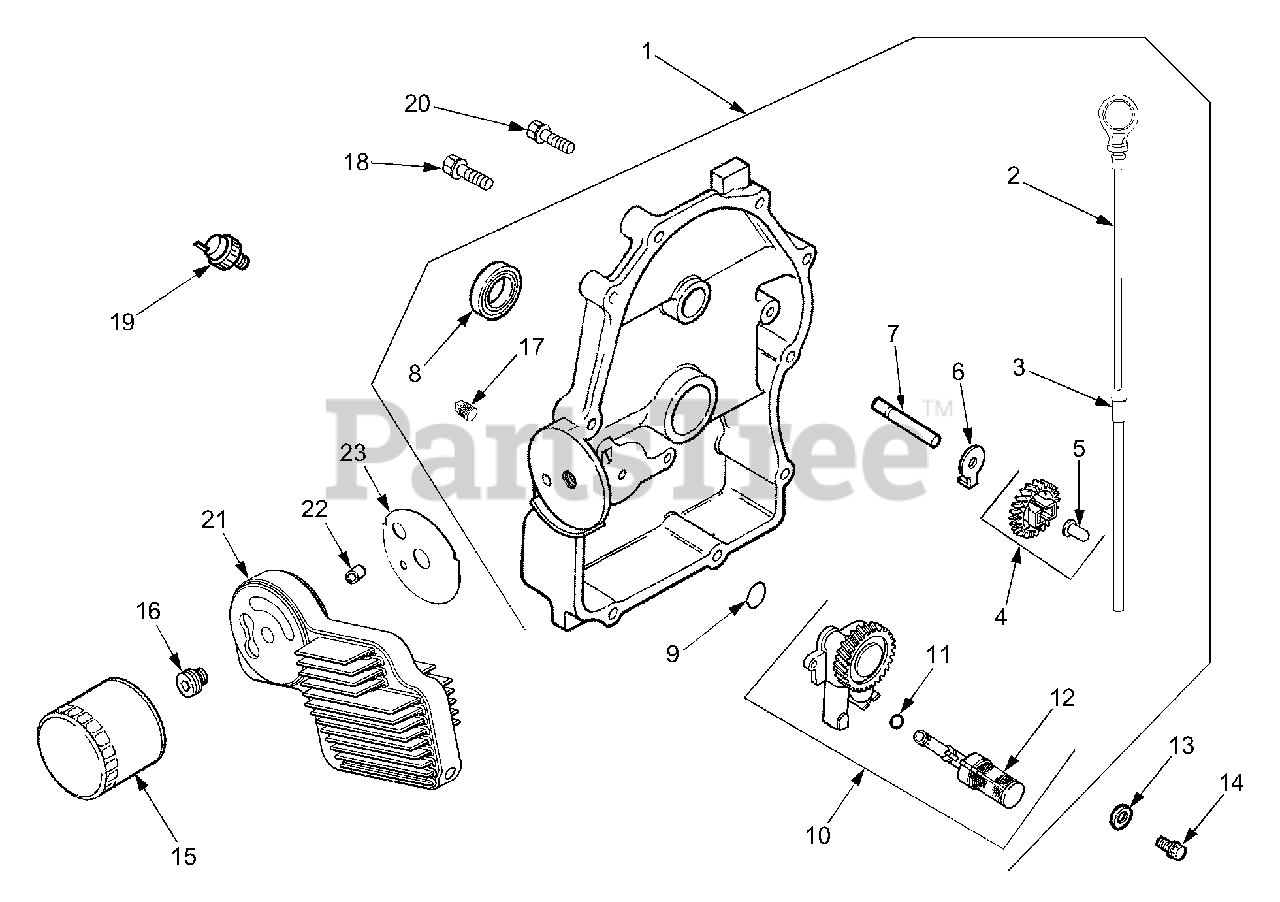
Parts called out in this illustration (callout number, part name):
1	Plate, Closure Assembly
3	Tube, Dipstick
4	Kit, Governor Gear
5	Pin, Governor Regulating
6	Tab, Locking
7	Shaft, Governor Gear
8	Seal, Oil (PTO End)
10	Oil Pump Assembly
11	O-Ring, Oil Pick-Up
12	Pick-Up, Oil
13	Washer, Plain
14	Screw, Hex Flange M6 x 1 x 25
15	Filter, Oil
16	Nipple, Oil Filter
17	Plug, Pipe 1/8"
18	Screw, Hex Flange M8 x 1.25 x 45
19	Switch, Pressure
20	Screw, Hex Flange M8 x 1.25 x 45
22	Pin, Locating
23	Gasket, Adapter
